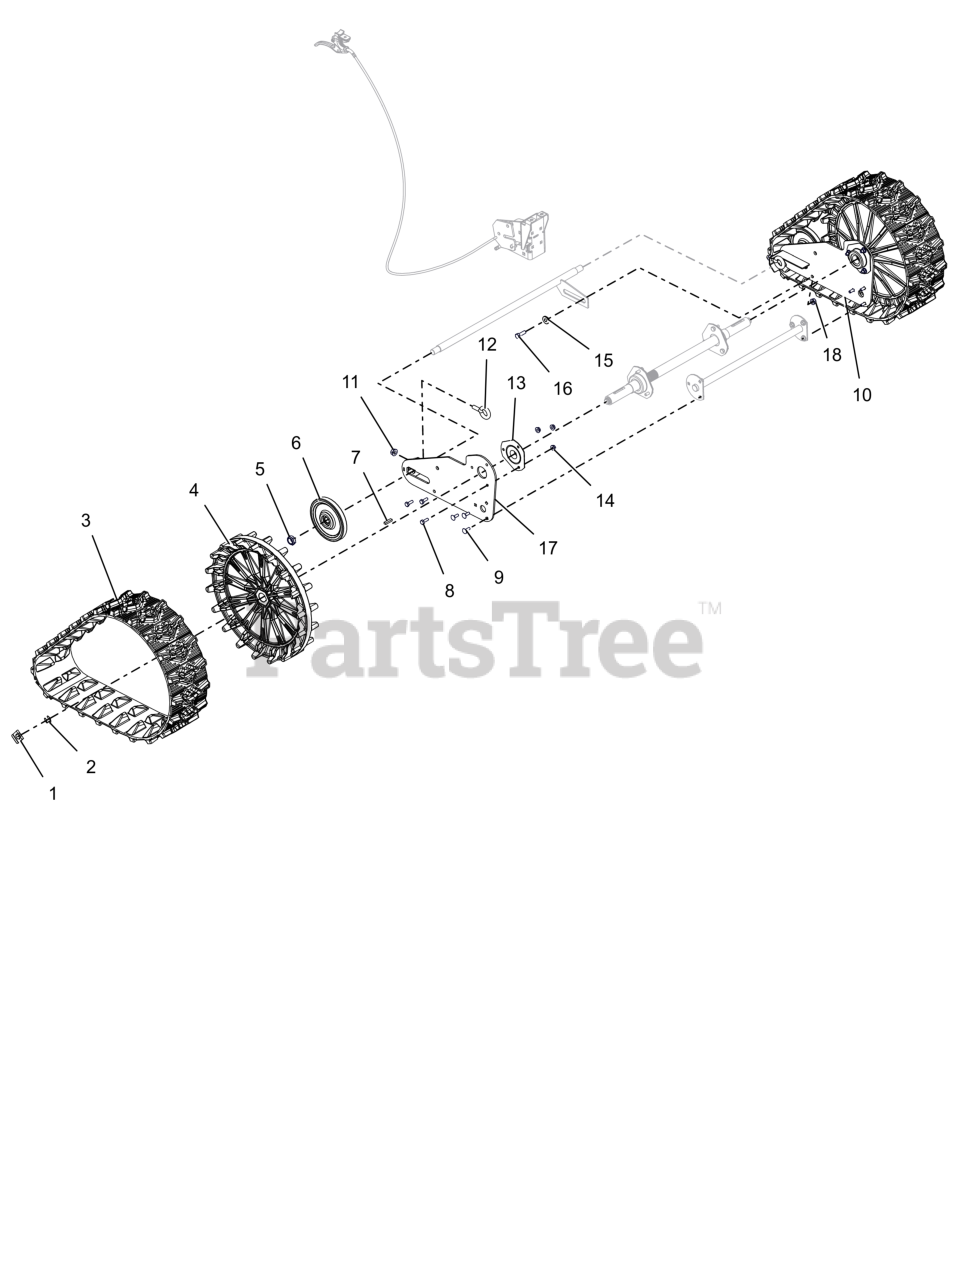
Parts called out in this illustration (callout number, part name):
1	CLIP, SNAP .625 DIA
2	RG-RTNG-EXT .625X.042
3	TRACK, RUBBER - 22 PITCHES
4	SPROCKET, LARGE TRACK DRIVE
5	NUT, NYL LK .625-18 ZCC
6	WHEEL, BOGIE - SINGLE BEARING
7	KEY-RECT .25X.188X1.00
8	BLT, HEX .25-20X.75 G5 ZCC
9	BLT, RHSN .25-20X.750 G5 ZCC
10	PLATE, SIDE-BWT LH WLDMT
11	NUT-LK-CTR-FLG .375-16 GF ZCC
12	BLT-EYE .375-16X.880 YWZC
13	BRG-FLG 1.003/1.000 3 BOLT
14	NUT-LK-TOP-FLG .250-20 GF ZCC
15	BSHG-FLG .325X.499X.3X.875
16	BLT,HEX .31-18X1.00 G5 ZCC
17	PLATE, SIDE-BWT RH WLDMT
18	NUT-LK-TOP-FLG .312-18 GF ZCC
